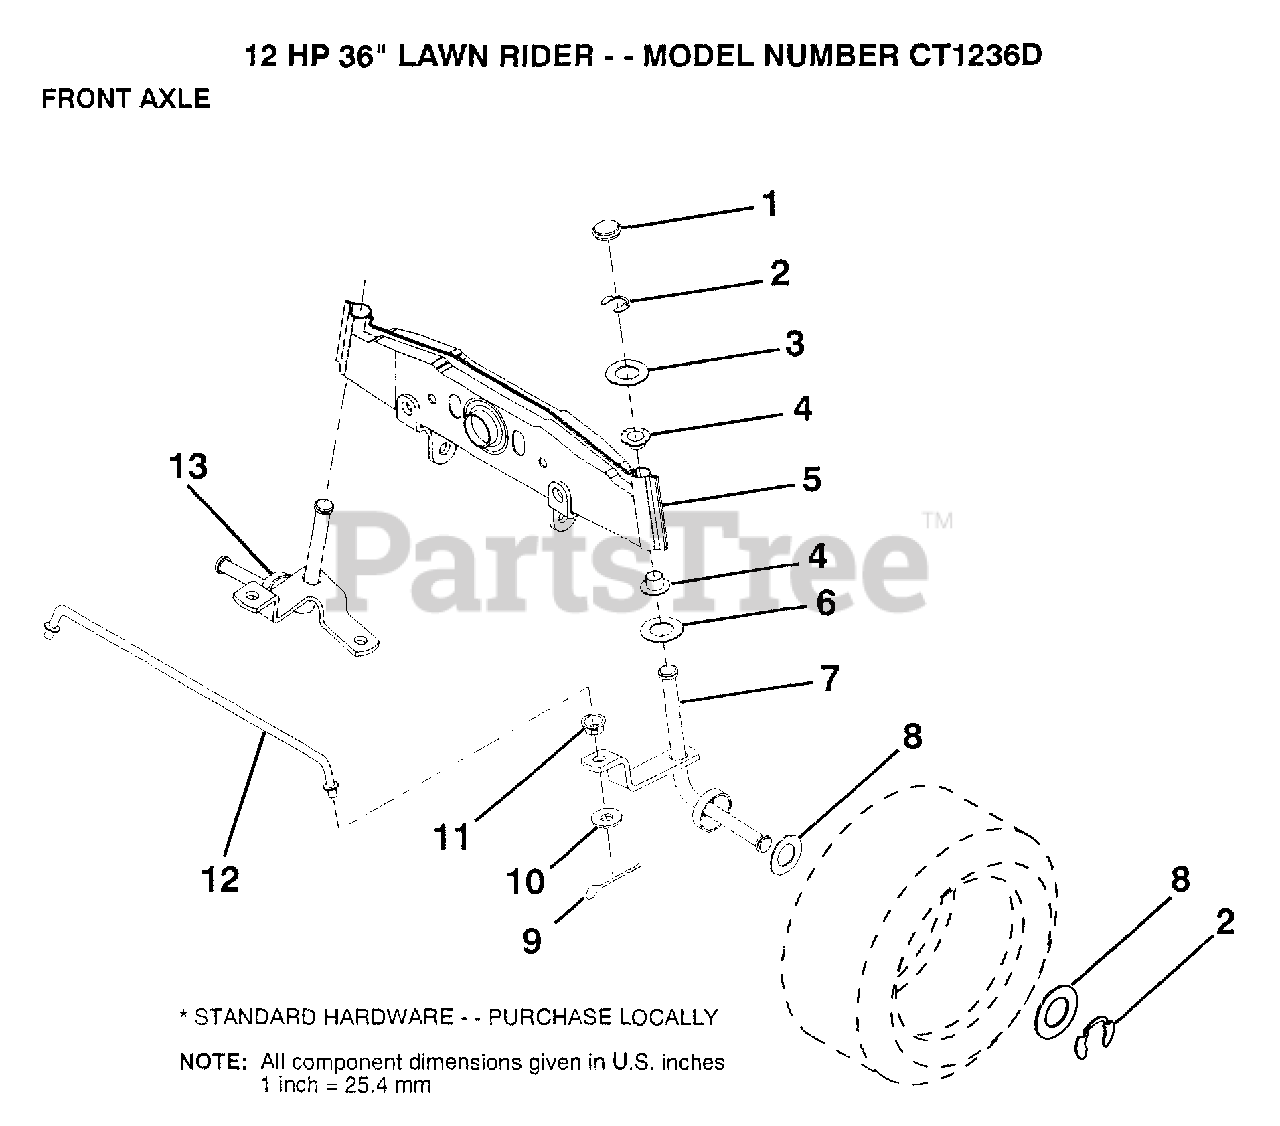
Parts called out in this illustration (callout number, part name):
1	CAP
2	RING
3	WASHER
4	NYLINER
6	WASHER .T
7	SPINDLE RH
8	WASHER
9	COTTER PIN
10	WASHER
11	BUSHING.DRAGLINK
12	ROD TIE
13	SPINDLE LH
